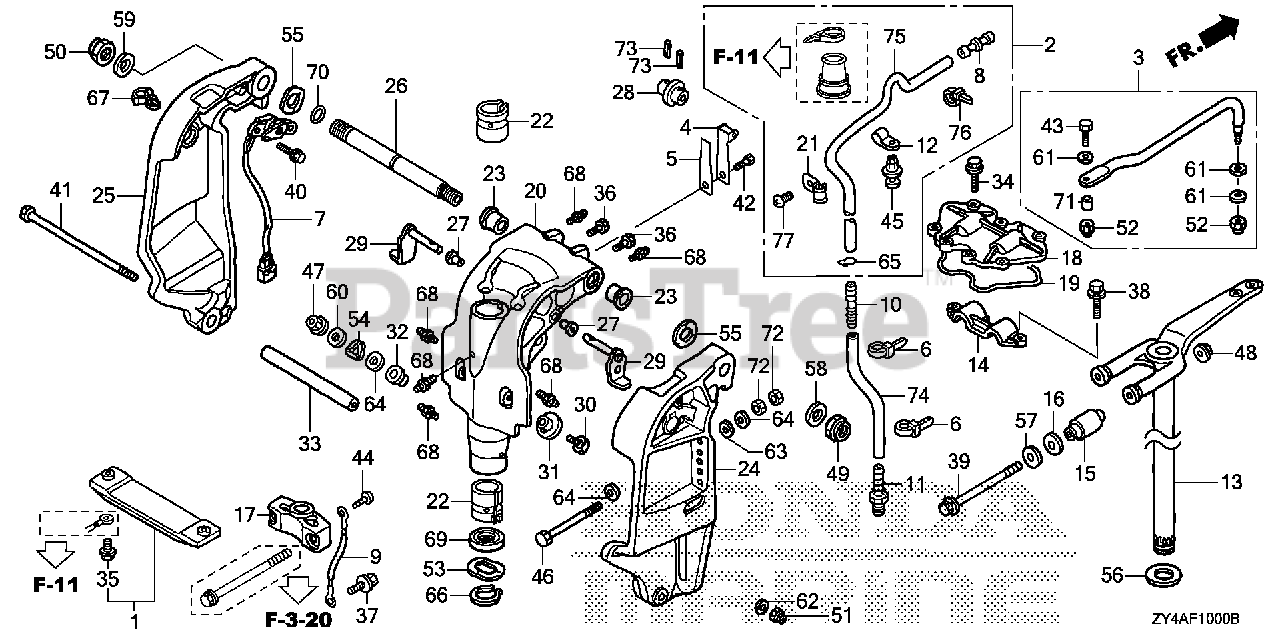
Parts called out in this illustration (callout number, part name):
1	METAL KIT, ANODE
2	TUBE KIT, SPEED SENSOR
3	ROD KIT, STEERING
4	SPRING, CLICK
5	SPRING, CLICK ASSIST
6	BAND, WIRE
7	SENSOR ASSY., TRIM ANGLE
8	JOINT B, WASHER TUBE (MITSUBA)
9	WIRE, LEAD (1.5X116MM)
10	END, NIPPLE
11	NIPPLE, SENSOR
12	CLAMP, SENSOR TUBE
13	FRAME, MOUNTING (L)
14	HOUSING, MOUNTING (UPPER)
15	MOUNT, RUBBER (UPPER)
16	RUBBER, MOUNT STOPPER (UPPER)
17	HOUSING, CENTER MOUNTING (LOWER) *NHB14M* (AQUA MARINE SILVER METALLIC)
17	HOUSING, CENTER MOUNTING (LOWER) *NH565* (GRAND PRIX WHITE)
18	COVER, MOUNT (UPPER)
19	SEAL, MOUNT COVER (UPPER)
20	CASE, SWIVEL *NHB14M* (AQUA MARINE SILVER METALLIC)
20	CASE, SWIVEL *NH565* (GRAND PRIX WHITE)
21	CLAMP, TUBE
22	LINER, SWIVEL CASE
23	BUSH, SWIVEL CASE
24	BRACKET, R. STERN *NHB14M* (AQUA MARINE SILVER METALLIC)
24	BRACKET, R. STERN *NH565* (GRAND PRIX WHITE)
25	BRACKET, L. STERN *NHB14M* (AQUA MARINE SILVER METALLIC)
25	BRACKET, L. STERN *NH565* (GRAND PRIX WHITE)
26	SHAFT, TILTING
27	BUSH, TILT ARM
28	BRACKET, TILTING
29	STOPPER, TILT
30	RECEIVER, THRUST
31	BUSH A, THRUST RECEIVE
32	BUSH B, THRUST RECEIVE
33	COLLAR, CYLINDER (LOWER)
34	BOLT, FLANGE (6X20)
35	BOLT, FLANGE (6X23)
36	BOLT (1/4-28UNF)
37	BOLT, FLANGE (6X12)
38	BOLT-WASHER (10X32)
39	BOLT, HEX. (12X200)
40	BOLT, FLANGE (6X20)
41	BOLT, HEX. (10X235)
42	BOLT, HEX. (6X14)
43	BOLT (3/8-24UNF)
44	SCREW, PAN (6X8)
45	SCREW, RIVET (5X10)
46	BOLT, HEX. (12X130)
47	NUT, SELF-LOCK (6MM)
48	NUT, FLANGE (12MM)
49	NUT, SELF-LOCK (7/8-14UNF)
50	NUT, SELF-LOCK (25X2.0)
51	NUT, FLANGE (10MM)
52	NUT, SELF-LOCK (3/8-24UNF)
53	WASHER, WAVE (40MM)
54	WASHER, WAVE (12MM)
55	WASHER, WAVE (26MM)
56	WASHER, THRUST (34MM)
57	WASHER, MOUNTING STOPPER (UPPER)
58	WASHER (7/8")
59	WASHER (25MM)
60	WASHER, PLAIN (6MM)
61	WASHER (10MM)
62	WASHER, PLAIN (10MM)
63	WASHER, PLAIN (12MM)
64	WASHER, PLAIN (12MM)
65	CLIP, TUBE (B8)
66	CIRCLIP (OUTER) (39MM)
67	CLIP, WIRE HARNESS
68	NIPPLE, GREASE
69	OIL SEAL (39.5X52X6) (ARAI)
70	O-RING (15.54X2.62)
71	COLLAR, STEERING ROD
72	NUT, HEX. (12MM)
73	PIN, SPRING (3X20)
74	BULK HOSE, VACUUM (5X3000) (5X200)
75	BULK HOSE, VACUUM (5X3000) (5X950)
76	BAND, WIRE
77	SCREW, PAN (6X8)
